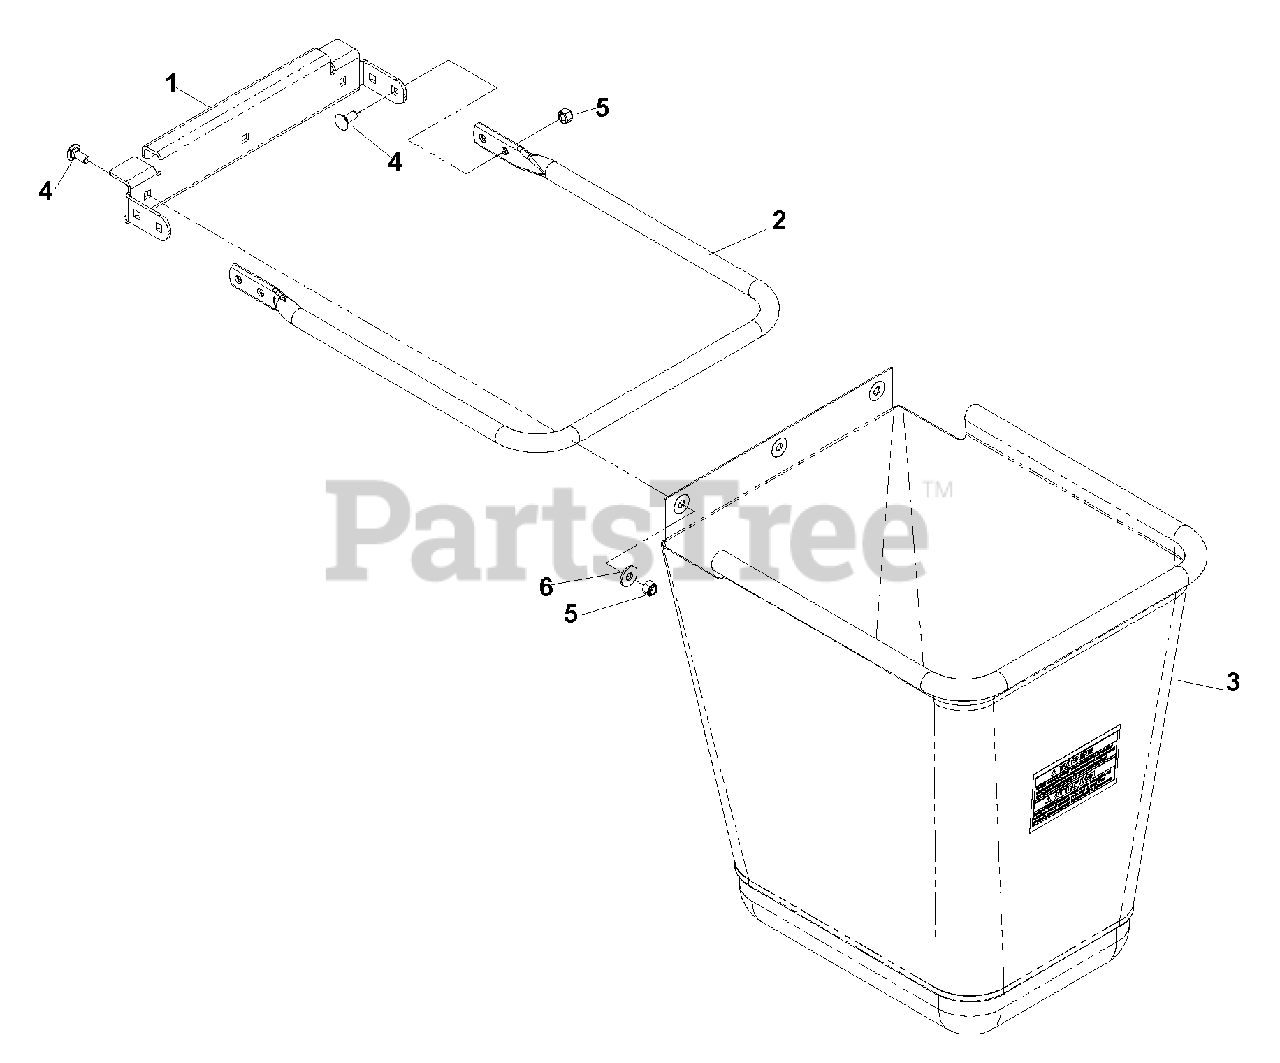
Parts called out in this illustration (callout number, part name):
1	HANGER, BAG
2	TUBE, BAG FRAME
3	BAG, LARGE
4	RHSNB, 5/16 -18 x 5/8,
5	NUT, 5/16, NYLOC
6	WASHER, 5/16
